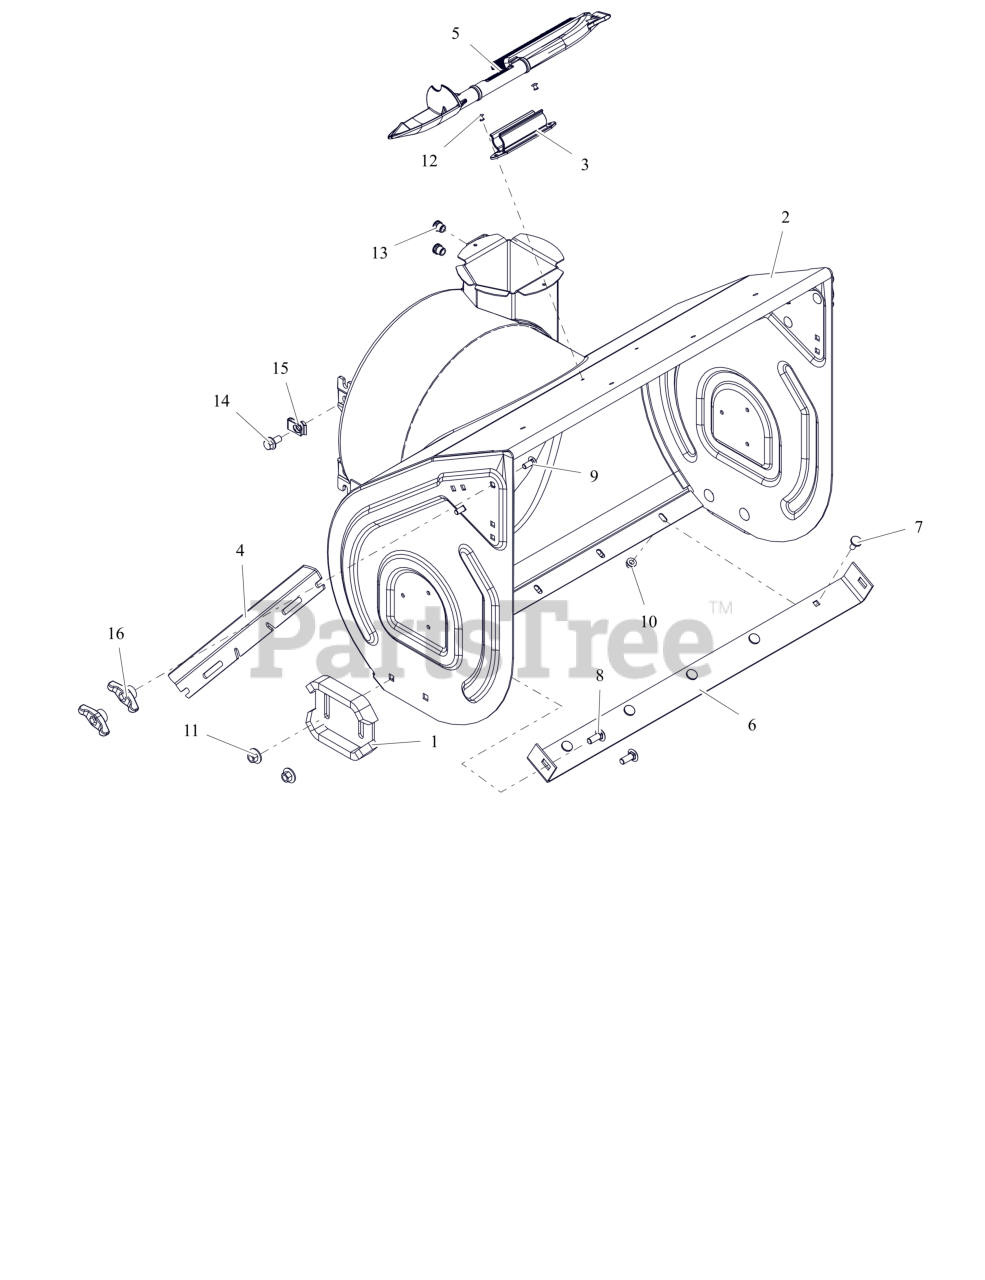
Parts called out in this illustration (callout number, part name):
1	RUNNER, SKID SHOE
2	HOUSING, PRO W/DECAL 28"
3	MOUNT, SNOW CLEAN OUT
4	CUTTER, DRIFT
5	DEVICE, SNOW CLEAN OUT W/BRUSH
6	BLADE, SCRAPER-28"
7	BOLT, MODIFIED HEAD CARRIAGE
8	BLT,RHSSN .38-16X1.00 G5 ZCC
9	BLT, RHSSN.31-18X.750 G5 ZCC
10	NUT-LK-TOP-FLG .312-18 GF ZCC
11	NUT- CON-LN .375-16 ZC120
12	RVT, POP .1875 ZCC
13	NUT,THD,INSERT .38-16 ZC120
15	NUT-RTNR .375-16X.37
16	KNOB,WING .31-18 UNC NYL/TALC
